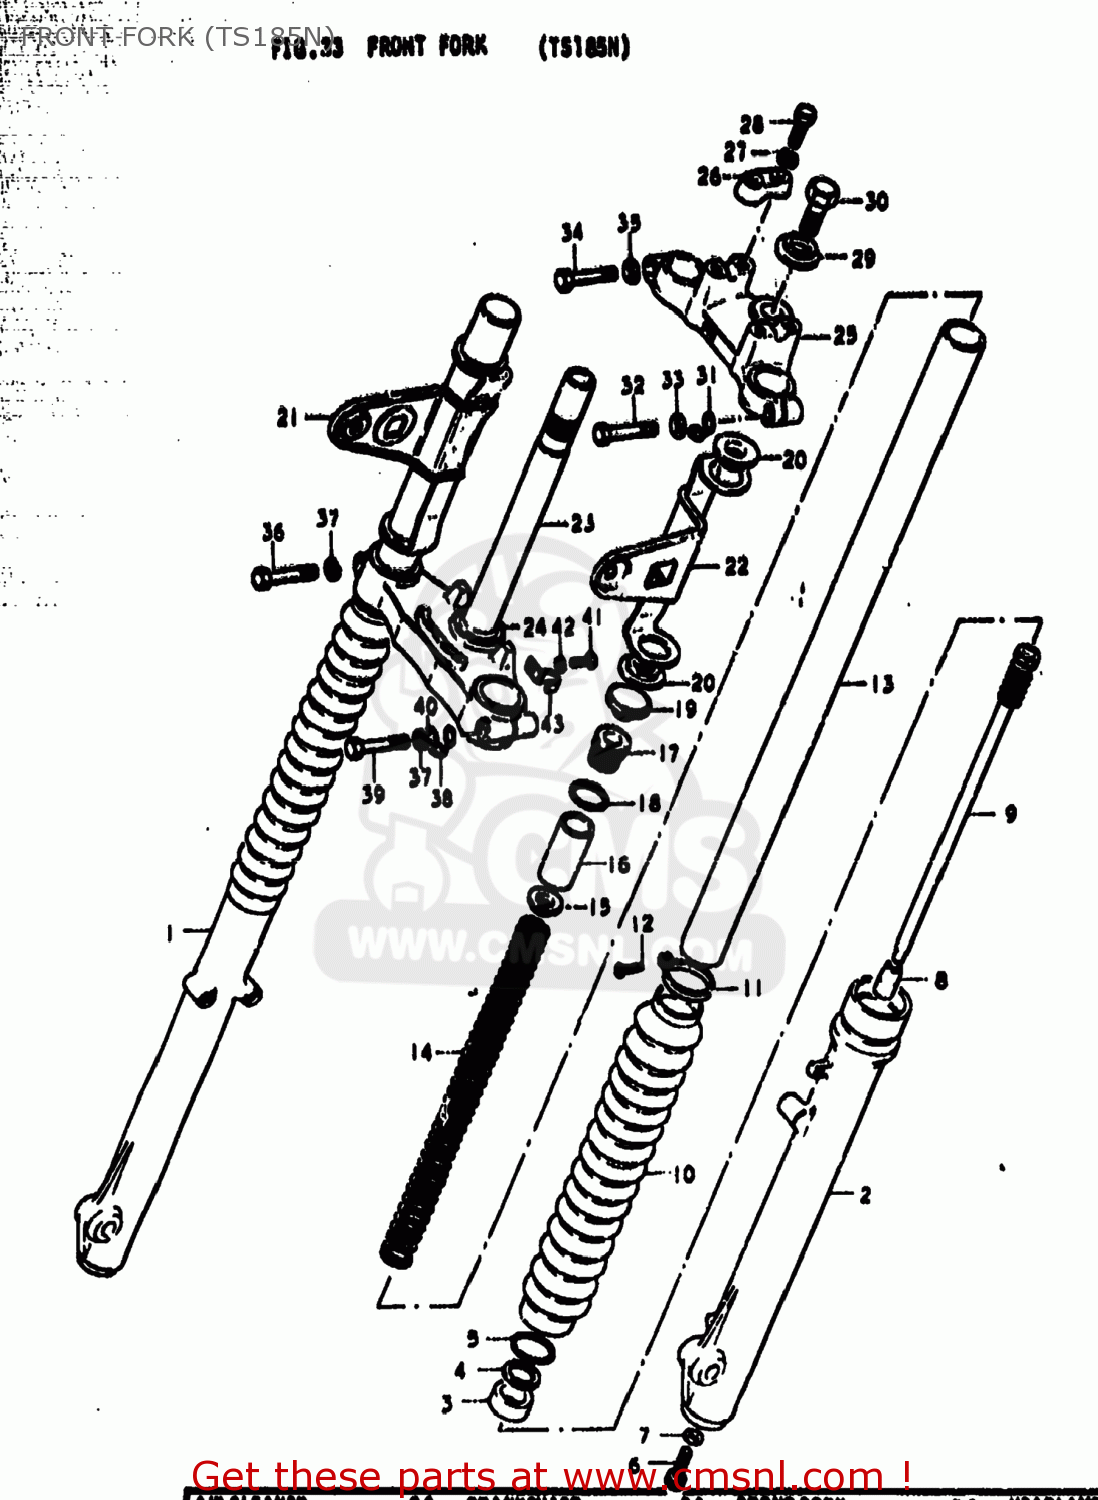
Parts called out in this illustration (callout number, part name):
1	TUBE,FORK,OUTER,RIGHT
2	TUBE,OUTER,LEFT
3	OIL SEAL,FRONT FORK
4	WASHER
5	RING,SNAP
6	BOLT,FORK CYLINDER(10X25)
7	GASKET (NAS)
8	PIECE,OIL LOCK
9	CYLINDER,FRONT FORK
10	BOOT
11	BAND,FORK COVER BOOT
12	SCREW
13	TUBE,FORK,INNER
14	SPRING
15	GUIDE,SPRING COVER
16	SPACER,SPRING
17	CAP
18	O-RING,FORK INNER TUBE
19	CAP,FRONT FORK
20	CUSHION,HEADLAMP BRACKET
21	BRACKET,HEADLAMP HOUSING
22	BRACKET,HEADLAMP,LEFT
23	STEM,STEERING
24	RACE,STEERING OUTER LWR
25	HEAD,STEERING STEM
26	HOLDER,HANDLE(BLACK)
27	LOCK WASHER
28	BOLT
29	WASHER,STEM HEAD(10.5X30X3.2)
30	BOLT,FORK INNER TUBE
31	CLIP
32	BOLT 10X40
33	WASHER
34	BOLT,FORK INNER TUBE F
35	LOCK WASHER
36	BOLT
37	WASHER,LOCK 12
38	CLIP
39	BOLT 12X45
40	WASHER
41	SCREW
42	LOCK WASHER
43	CLIP,BRAKE CABLE
